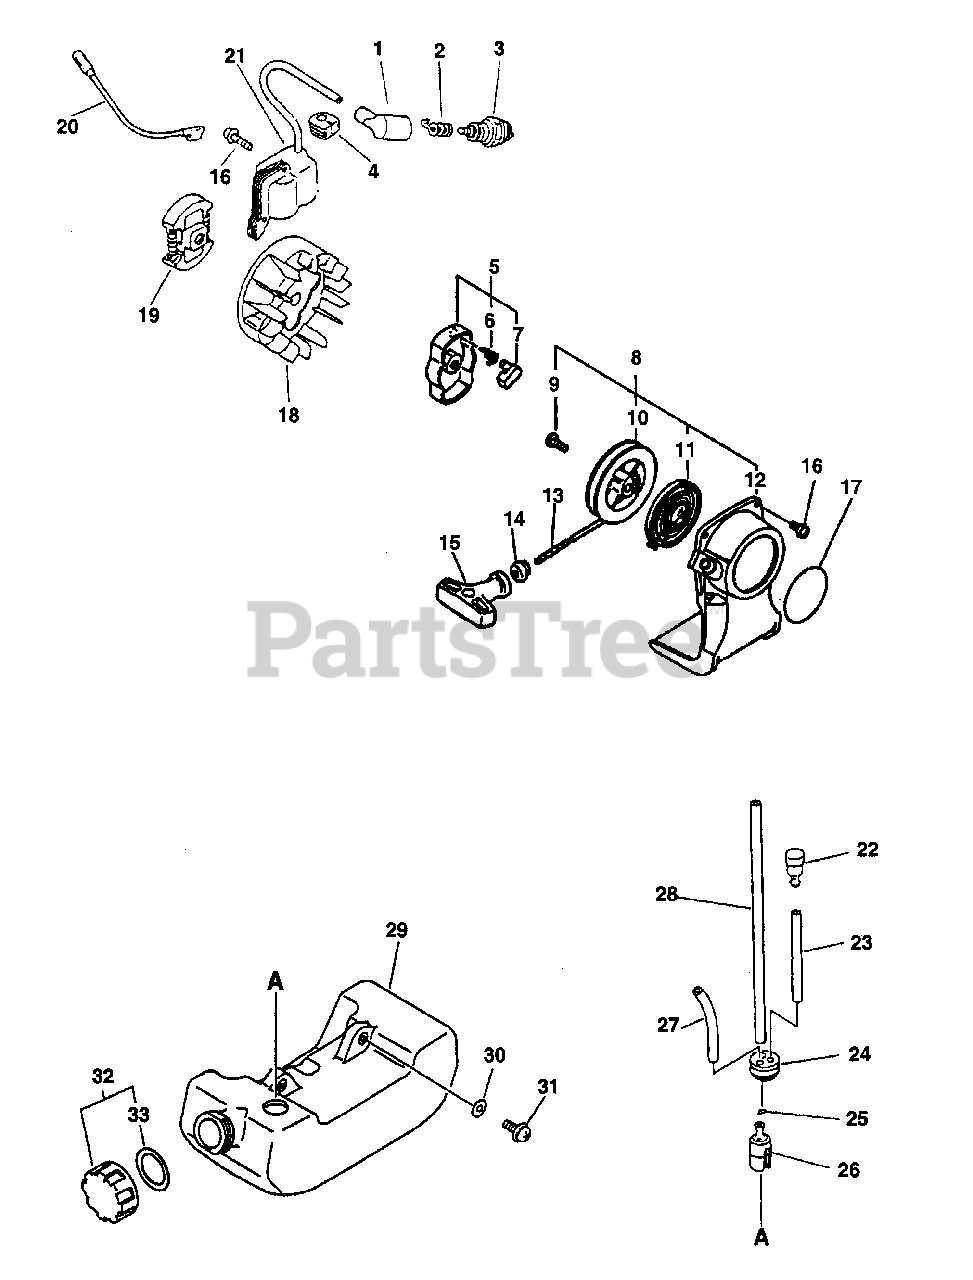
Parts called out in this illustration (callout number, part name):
1	CAP, SPARK PLUG
2	COIL, SPARK PLUG CAP
3	PLUG, SPARK BPM-7A
3	PLUG, SPARK BPMR-7A
5	PAWL ASY, STARTER
6	SPRING, RETURN
7	PAWL, STARTER
8	STARTER ASY
10	DRUM, STARTER
11	SPRING, REWIND
12	CASE, STARTER
13	ROPE, STARTER
14	GUIDE, ROPE
15	GRIP, STARTER
16	BOLT, H.S. 4X22
17	LABEL, BRAND
18	FLYWHEEL
19	CLUTCH ASY
20	LEAD
21	COIL, IGNITION W/O LEAD
21	COIL, IGNTION
22	VENT ASY
23	PIPE 3X5X70L
26	STRAINER, FUEL
27	PIPE 3X6X90
28	PIPE, FUEL
29	TANK, FUEL
30	WASHER 5
31	SCREW 5X16
32	CAP ASY, FUEL TANK
33	GASKET, FUEL CAP
